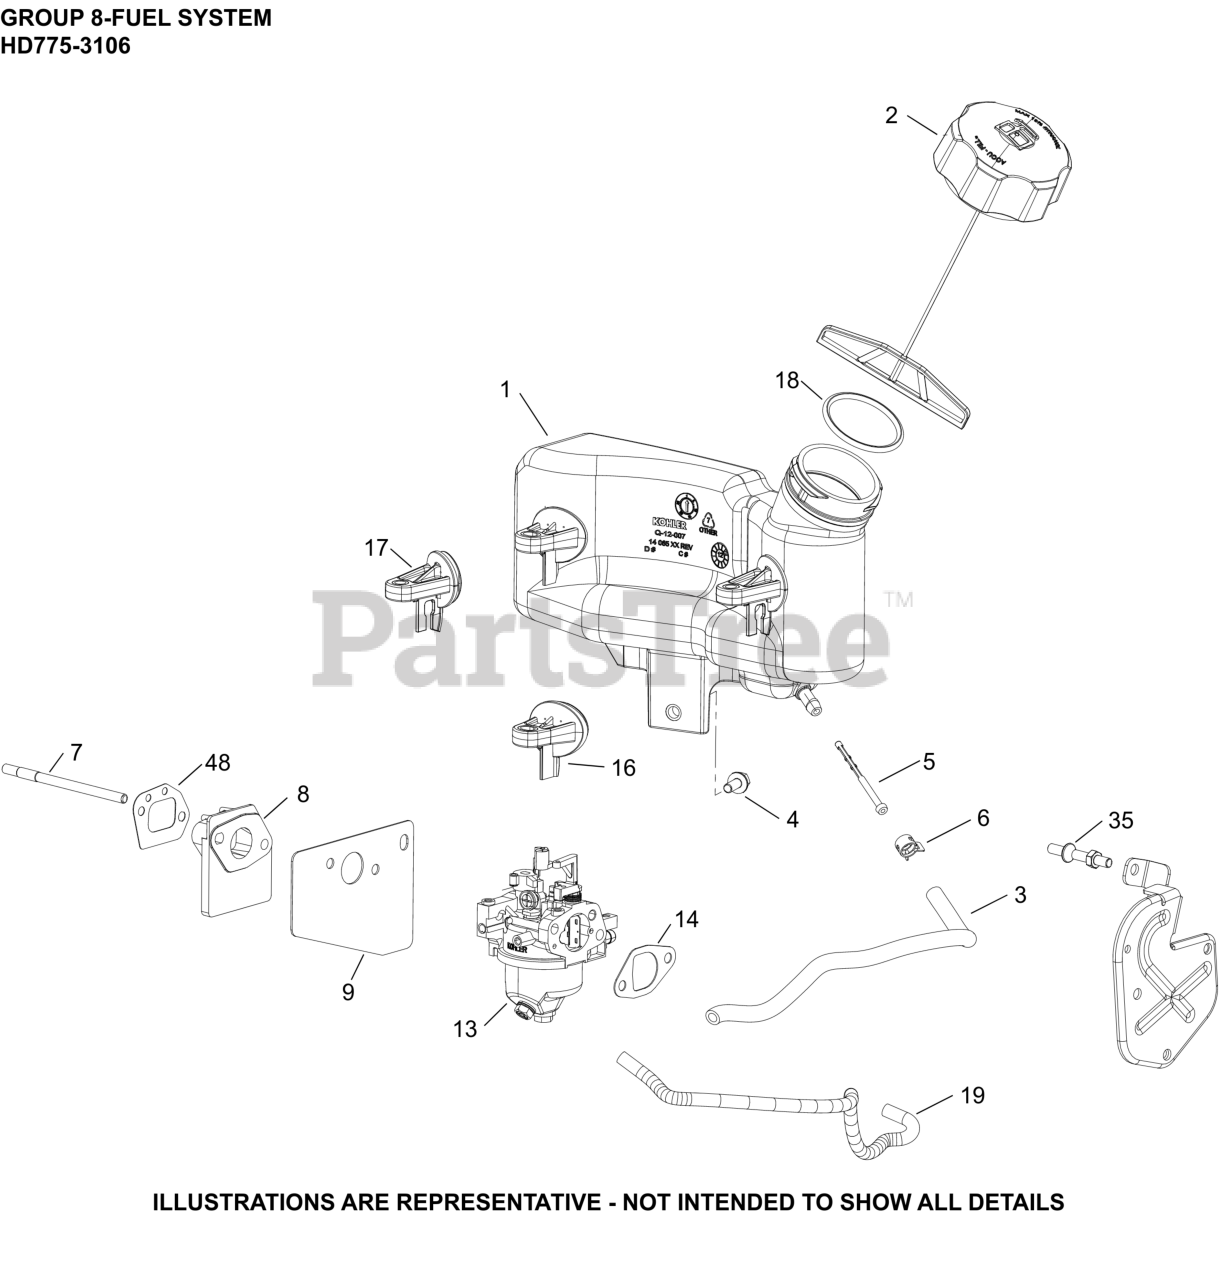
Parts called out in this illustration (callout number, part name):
1	TANK, FUEL
2	CAP ASSEMBLY, FUEL
3	HOSE, FUEL LOW-PERMEATION
4	SCREW, HEX FLANGE (M6)
5	FILTER, FUEL IN-NIPPLE
6	CLAMP, HOSE (NON-CALIF)(#1423710S)
7	STUD,M6X1.0X100.2MM
8	KIT, SPACER
9	KIT, CARBURETOR HEAT SHIELD GASKET
13	KIT, CARBURETOR 13 MM STD CHOKE
14	KIT, INTAKE GASKET
16	BRACKET, FUEL TANK-DISCONTINUED
17	BRACKET, FUEL TANK-DISCONTINUED
18	SEAL, FUEL CAP- (#DSC)
19	HOSE, EVAPORATIVE
48	GASKET SPACER
NI	TOOL, SPARK PLUG WRENCH ASSY
NI	KIT,HIGH AL(4000-8000 FT)USE 14 755 04-S
NI	KIT, CARBURETOR REPAIR (RUIXING)
